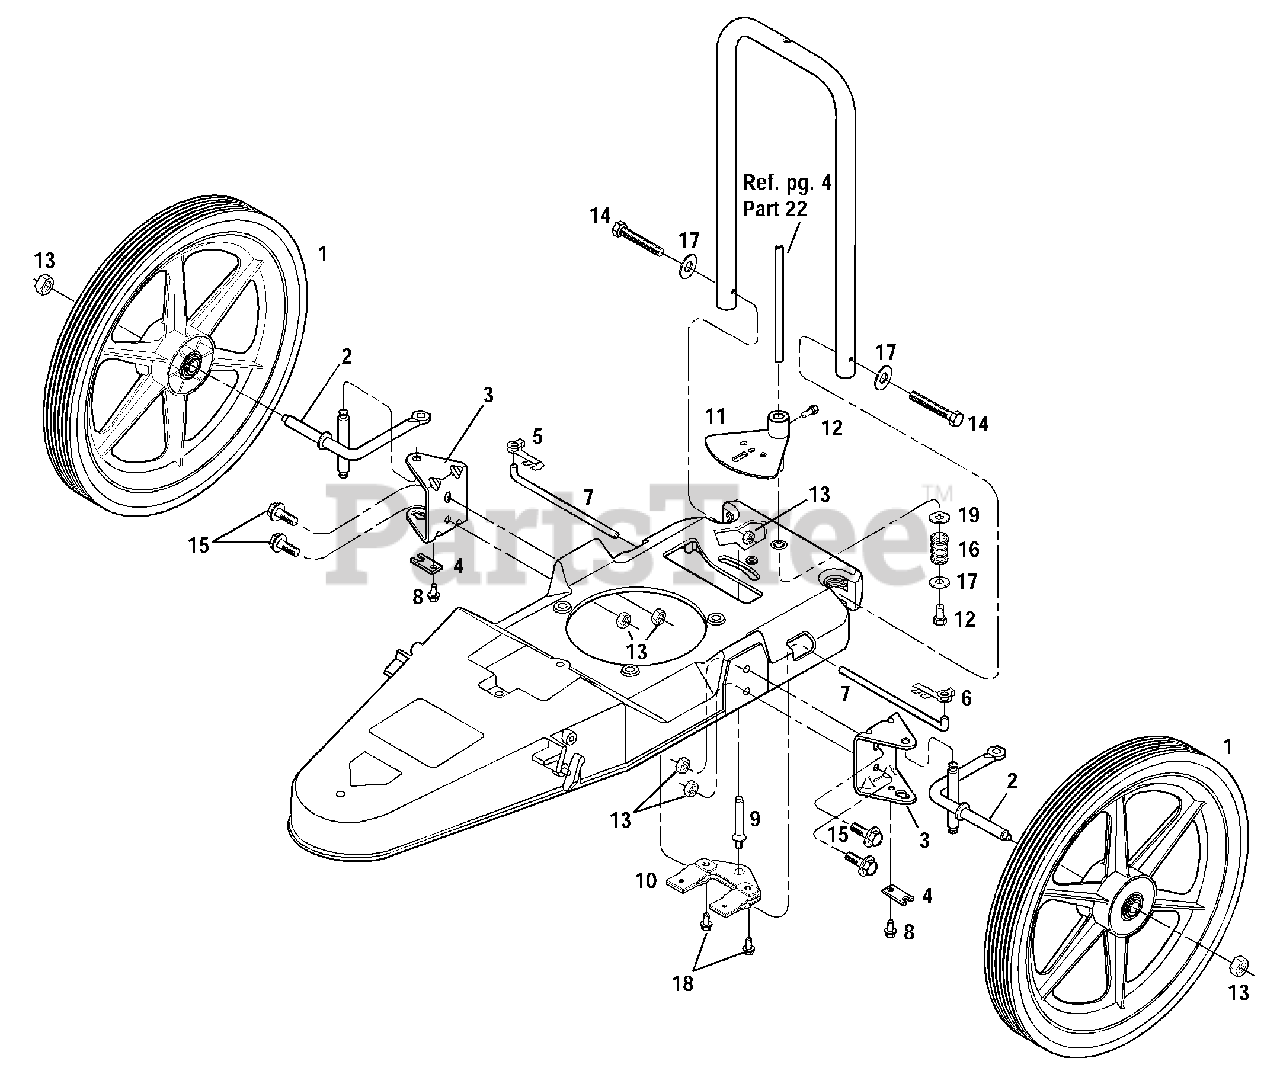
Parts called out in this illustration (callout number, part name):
1	Wheel - 6 spoke
2	Wheel Arm Weldment
3	Wheel Mounting Bracket
4	Wheel Arm Retainer
5	Rod End Clip/Right Side
6	Rod End Clip/Left Side
7	Steering Link
8	Hex Flange Screw, 1/4-20 x 5/8
9	Shoulder Stud
10	Clamp Link
11	Trim Plate
12	Screw, 5/16-24 x 1/2
13	Hex Lock Nut, 5/16-18
14	Hex Head Bolt, 5/16-18 x 2
15	Hex Flange Screw, 5/16-18 x 1
16	Spring
17	Washer, 5/16 ID
18	Hex Flange Screw, 5/16-18 x 5/8
19	Washer
